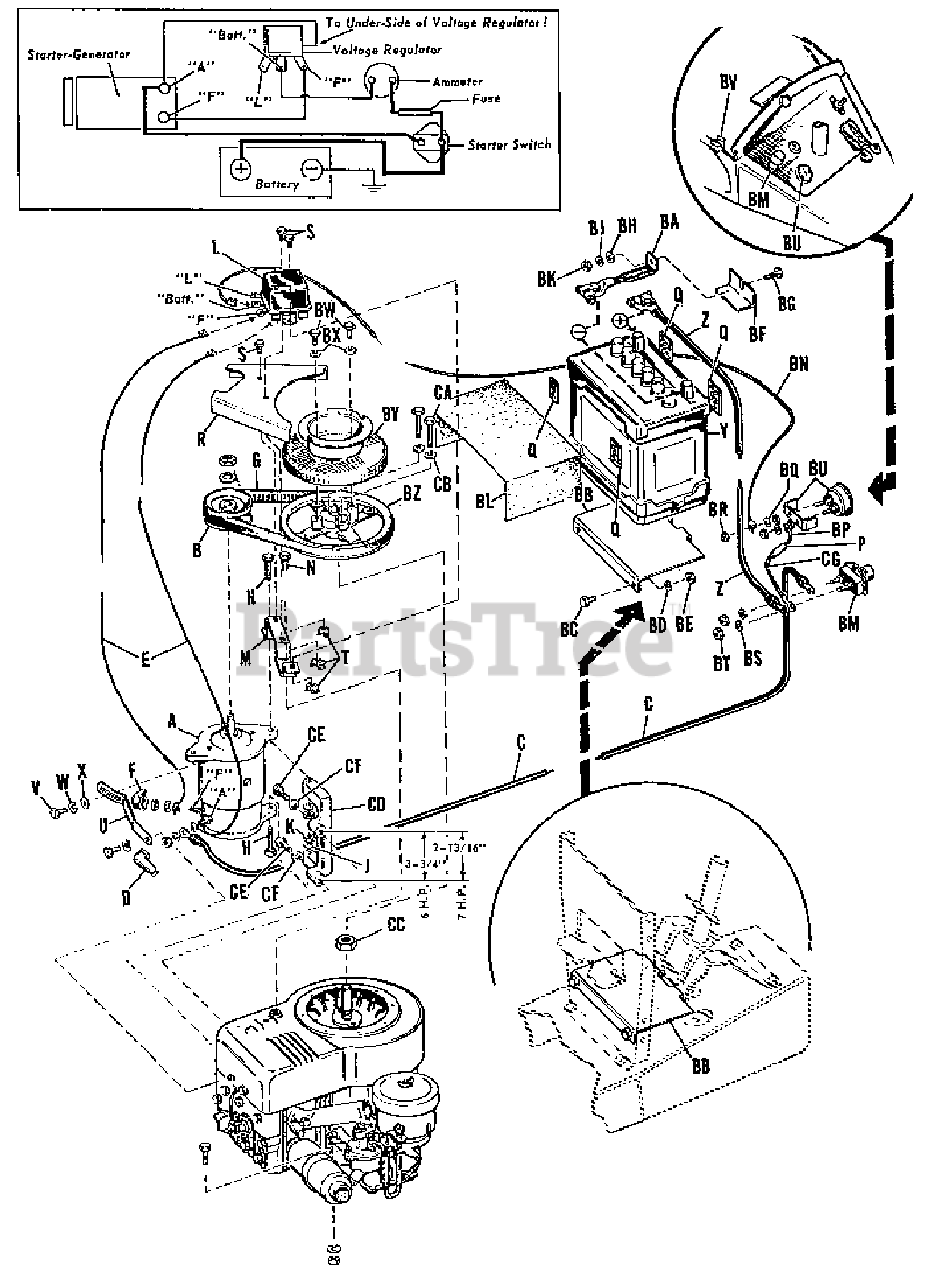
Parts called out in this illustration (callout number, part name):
A	MOTOR-GENERATOR
B	GENERATOR PULLEY
C	CABLE (Generator to Switch
D	TERMINAL, Cover
F	TERMINAL, Cover
H	HEX CAPSCREW, 5/16-18 x 1-3/4" Large
J	LOCKWASHER, 5/16"
K	HEX NUT, Full, 5/16-18
L	VOLTAGE REGULATOR
M	REGULATOR BRACKET
N	HEX CAPSCREW, 1/4"-20 x 5/8" Large
P	FUSE- 20 Amp
Q	FELT, Gasket
R	PULLEY, Guard
S	HEX, Capscrew, 1/4"-20 x 5/8" Large
T	TIMERMAN NUT
U	ADJUSTMENT STRAP
V	HEX, Capscrew, 5/16-18 x 3/4" Large
W	WASHER, Plain, 5/16
X	WASHER, Lock, 5/16
Z	BATTERY, Cable
BA	GROUND, Cable
BB	BATTERY, Support
BC	CAPSCREW, Hex, 1/4-20 X 5/8" Large
BD	LOCKWASHER, 1/4"
BE	NUT, Hex, Full 1/4-20
BF	BATTERY, Clamp
BG	CAPSCREW, Hex 1/4-20 x 3/4" Large
BH	WASHER, Plain 1/4"
BJ	WASHER, Lock, 1/4"
BK	NUT, Hex, Full, 1/4-20"
BL	BATTERY INSULATION
BM	STARTER SWITCH
BN	WIRE (Starter Switch To Regulator)
BP	WIRE (Fuse to Ammeter)
BQ	LOCKWASHER, 3/8"
BR	NUT, Hex, Full, 3/8-16"
BS	WASHER, Lock 1/4"
BT	NUT, Hex, Full, 1/4-20"
BU	AMMETER
BV	CLIP, Fuse
BW	CAPSCREW, Hex, 5/16-18 X 3/4" Large
BX	LOCKWASHER, 1/4"
BY	PULLEY AND SCREEN
BZ	PULLEY, Electric Starter
CA	CAPSCREW, Hex, 1/4-20 X 2-1/4" Large
CB	LOCKWASHER, 5/16"
CC	FLYWHEEL NUT
CD	STARTER MOUNTING BRACKET G HP ONLY (122189 Y HP ONLY)
CE	CAPSCREW, Hex, 5/16-19 x 1-3/4" Large
CF	LOCKWASHER, 5/16"
CG	WIRE (Fuse to Starter Switch)
